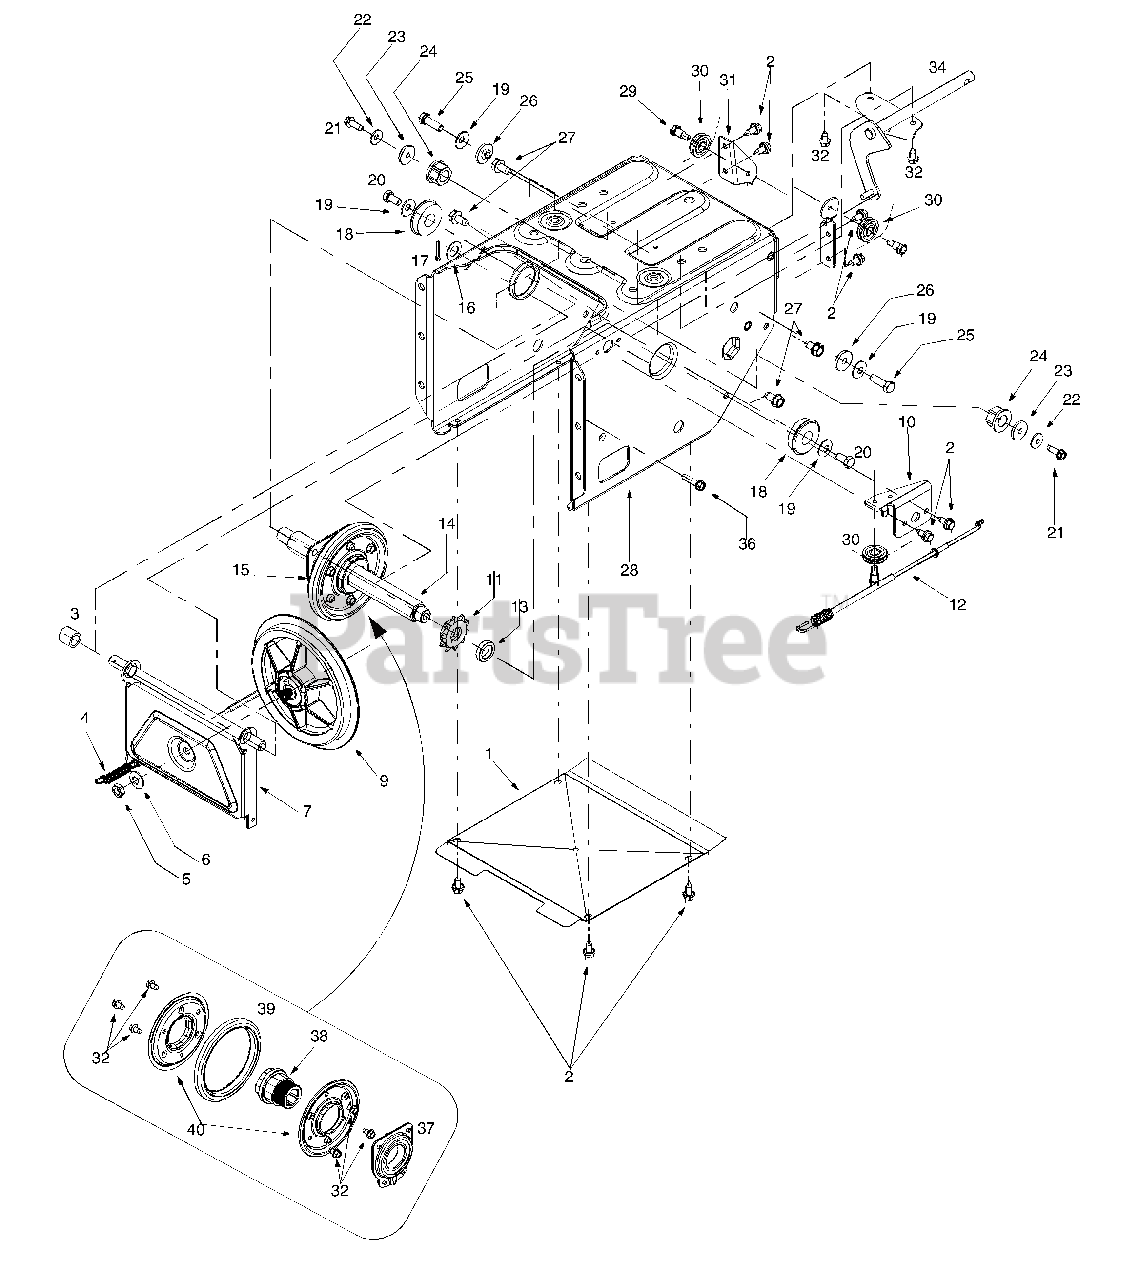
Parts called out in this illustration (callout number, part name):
1	Frame Cover
2	Tap Screw, 1/4-20 x .625
3	Spacer, .508 ID x .75 OD x .68
4	Ext. Spring
5	Jam Nut, 3/8-24
6	Bell Washer, .401 x .87 x .063
9	Friction Disc
12	Auger Cable, 44.75"
13	Spacer, .675 ID x 1 OD x .23
14	Hex Track Shaft
15	Friction Wheel Assembly
16	Flat Washer, .536 ID x .93 OD x .05
17	Cotter Pin
18	Ball Bearing
19	Bell Washer, .34 ID x .872 OD
20	Hex Cap Screw, 5/16-18 x .625
21	Tap Screw, 1/4-20 x .75
22	Bell Washer, .265 x .75 x .062
23	Flat Washer, 1/4 ID x .93 OD x .12
24	Hex Flange Bearing
25	Hex Cap Screw, 5/16-18 x 1
26	Shoulder Spacer
27	Tap Screw, 5/16-18 x .625
29	Spacer
30	Cable Roller
37	Friction Wheel Bearing
38	Friction Wheel Hub
39	Friction Wheel Rubber
40	Friction Plate
